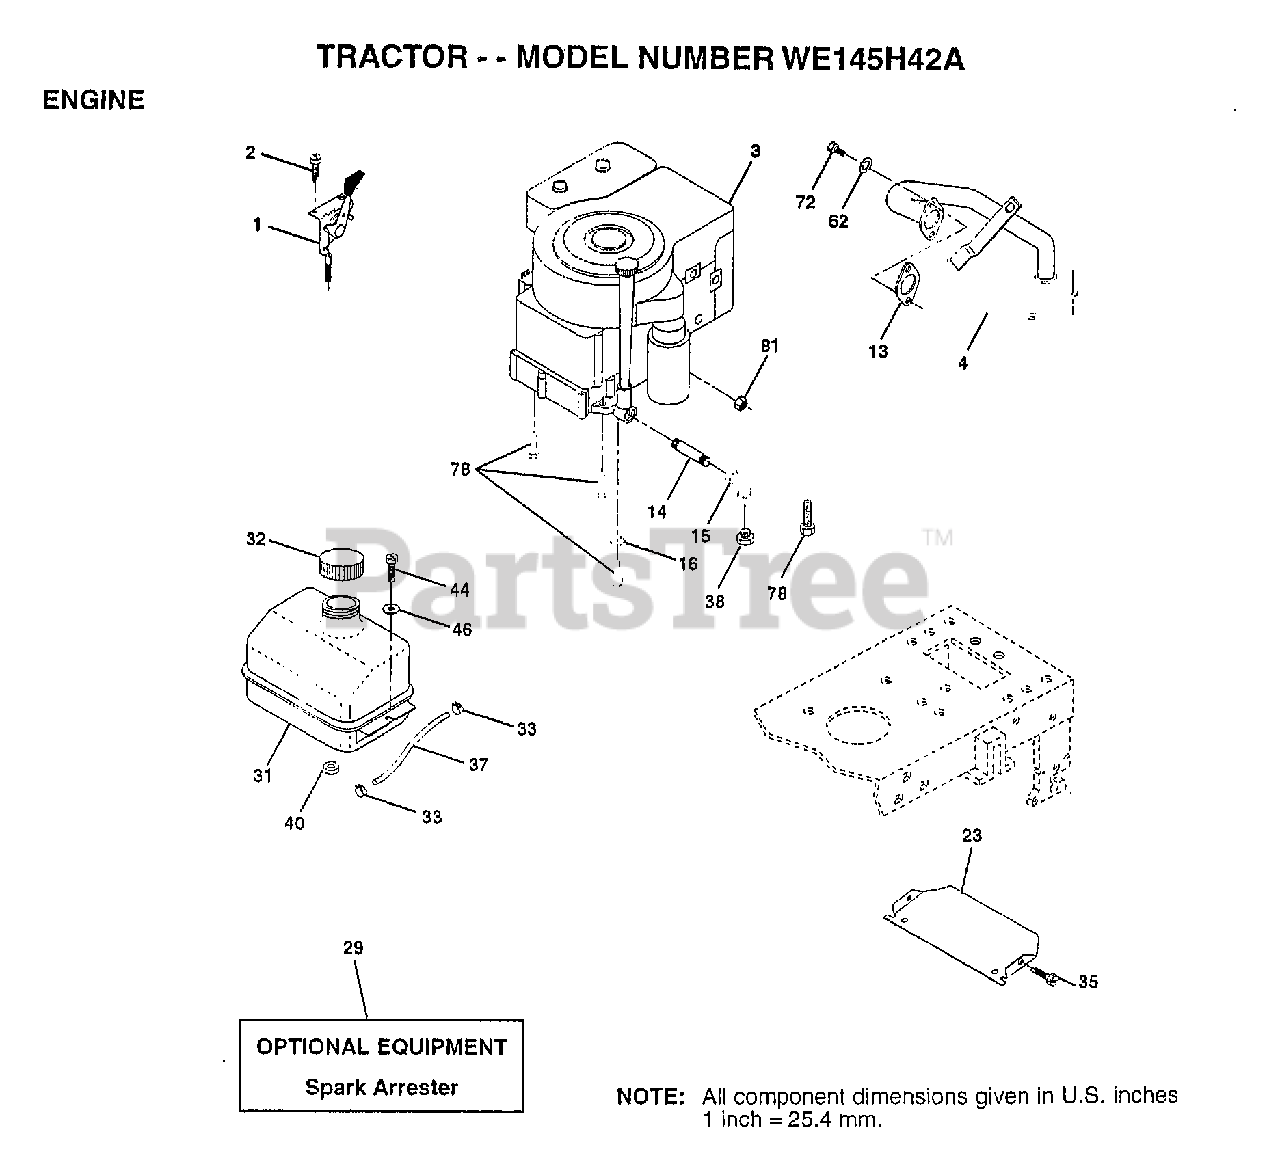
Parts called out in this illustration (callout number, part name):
1	CONTROL THROTTLE
2	SCREW LT
4	MUFFLER
13	GASKET ENG 1 313 LD TIN PLATED
14	PIPE NIPPLE
15	ELBOW
16	LOCKWASHER
23	SHIELD-HEAT
31	TANK.FUEL.LT.
32	CAP ASM FUEL
33	HOSE CLAMP
35	SCREW
37	LINE FUEL
44	SCREW HEX CRT
46	WASHER
62	LOCKWASHER
72	SCREW
78	SCREW
81	NUT
